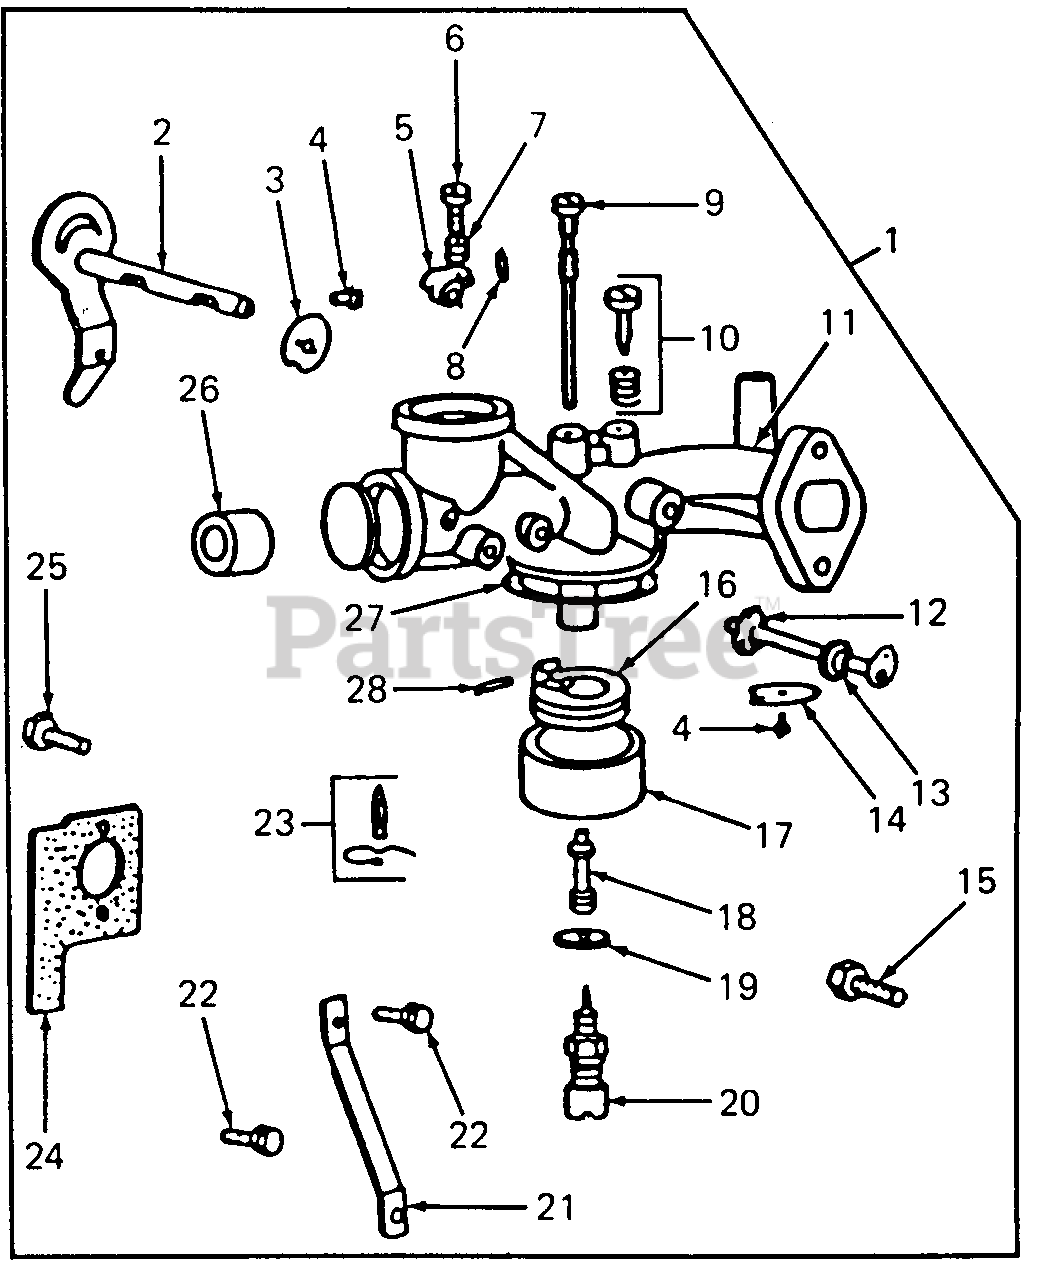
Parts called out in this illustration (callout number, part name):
1	Carburetor Assy
2	Shaft & Lever
3	Valve, Choke
4	Screw, Throttle & Choke Valve Mtg Sem
5	Stop, Throttle
6	Screw, Machine, Fill Hd 8-32 X 5/8
7	Spring, Throttle Adjustment
8	Pin, Throttle Stop
9	Nozzle, Carburetor
10	Valve Assy, Carburetor Idle
12	Seal, Throttle Shaft
13	Shaft & Lever, Throttle
14	Valve, Throttle
15	Screw, Control Casing to Screw
16	Float, Carburetor
17	Bowl, Float
18	Screw, Nozzle
19	Washer, Float Bowl
20	Valve, Needle
21	Bracket, Carburetor
22	Screw, Carburetor
23	Valve, Fuel Inlet
24	Gasket, Carburetor Mtg
25	Screw, Carburetor Mtg
26	Venturi, Carburetor Mtg
27	Gasket, Float Bowl
28	Pin, Float Hinge
